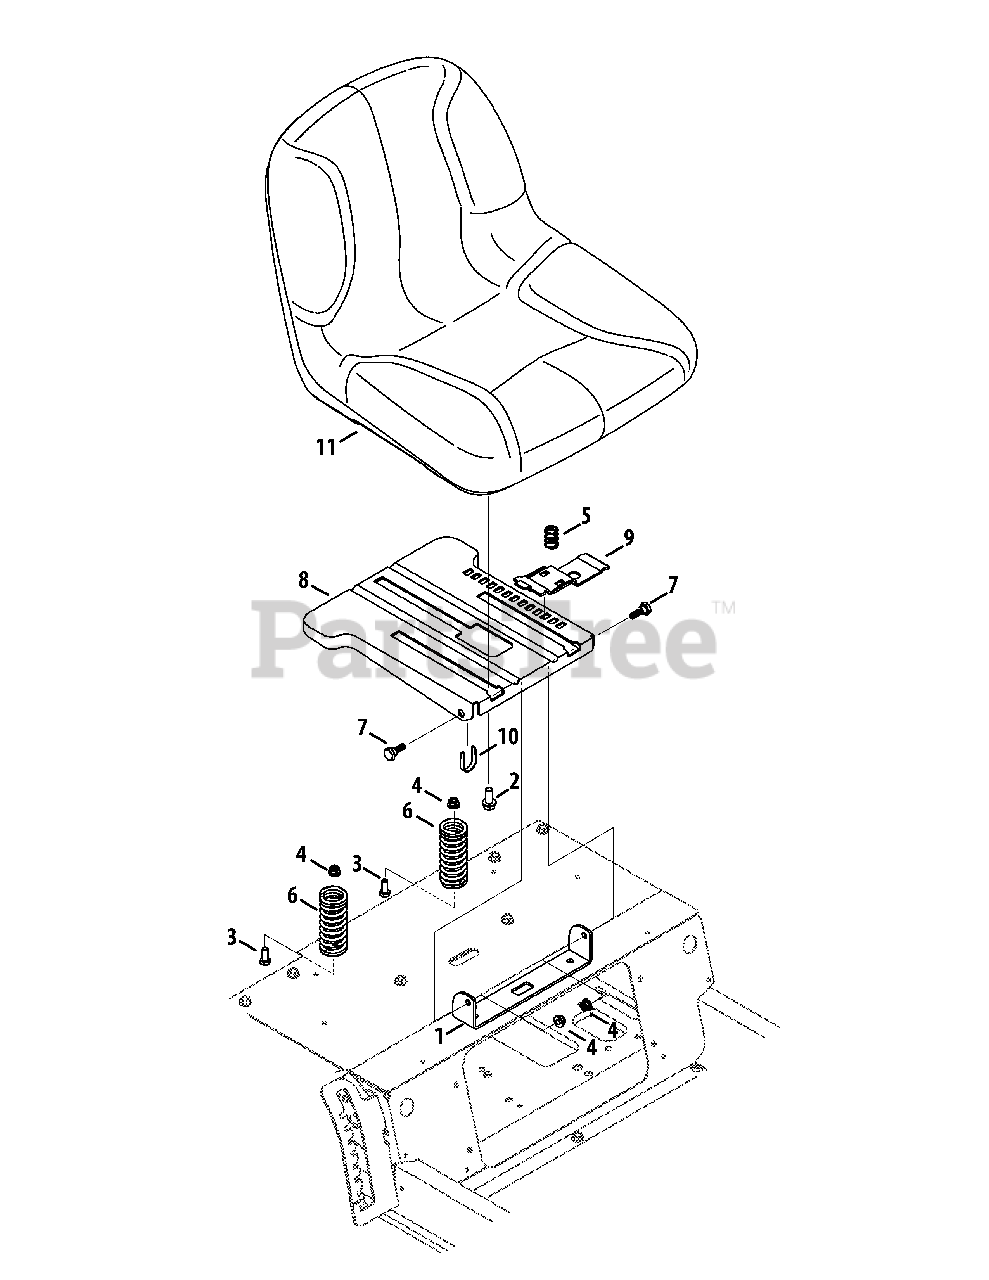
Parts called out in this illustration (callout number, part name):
2	Hex Flange Bolt, 3/8-16 x .875
3	Hex Cap Screw, 5/16-18 x .750
4	Flange Lock Nut, 5/16-18
5	Compression Spring, .68 x 1.065 x .055
6	Compression Spring, 1.50 x 3.90 x .200
7	Shoulder Screw, 5/16-18 x .437 x .268
8	Seat Mount Bracket
9	Seat Adjustment Lever
11	Seat
